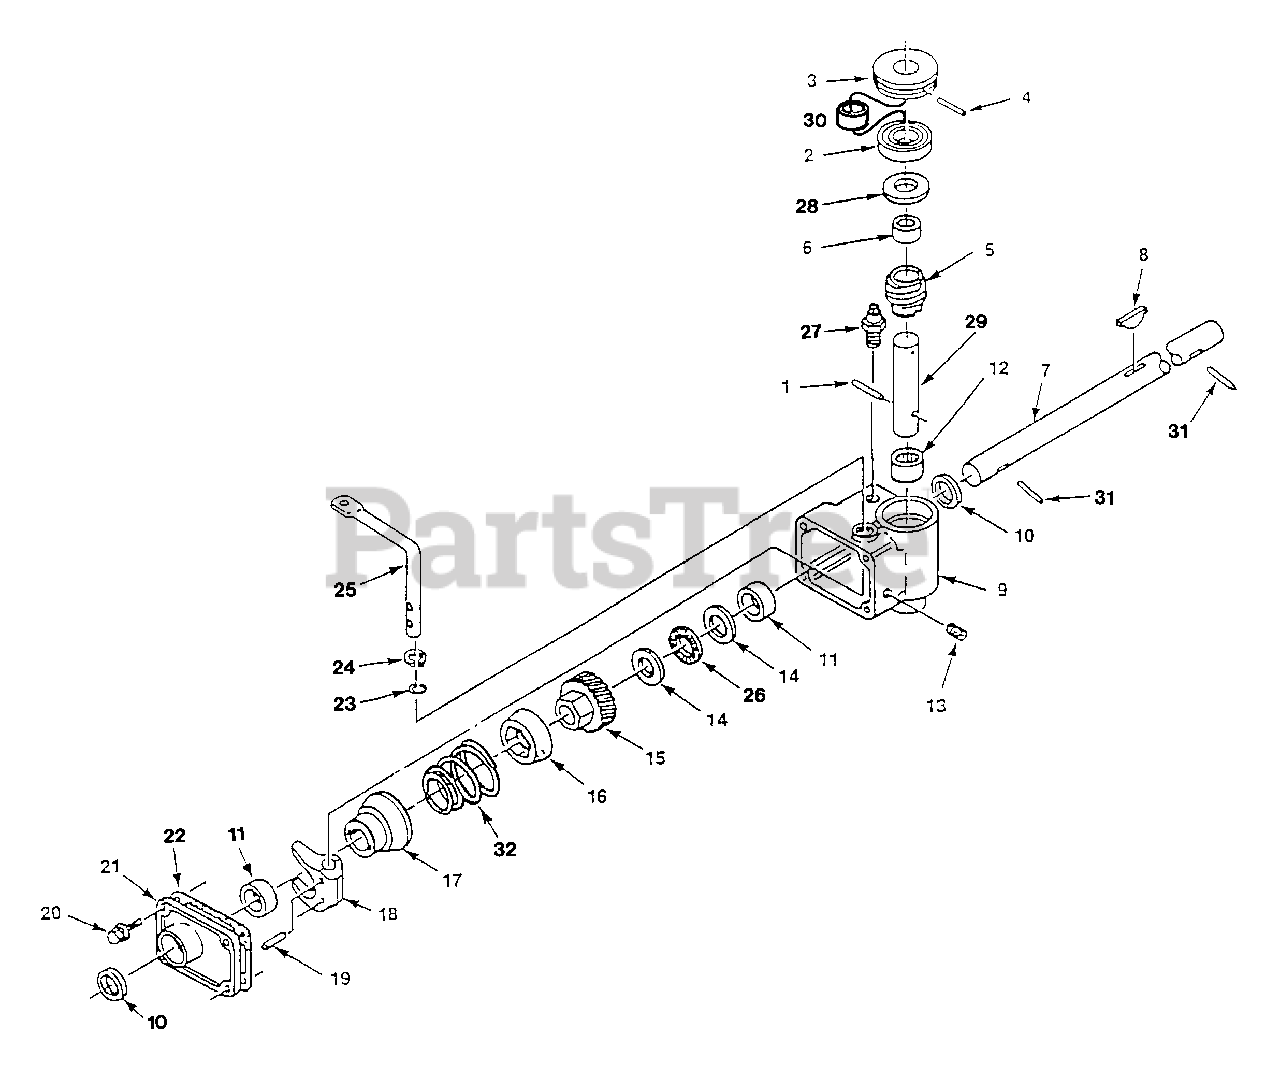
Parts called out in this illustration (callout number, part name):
1	Pin - Roll 3/16 x 7/8
2	Bearing - bail
3	Pulley - drive
4	Pin - Roll 3/32 x 1-1/4
5	Worm w/spacer
6	Spacer - worm
7	Shaft - drive
8	Key - Woodruff
9	Housing - gear
11	Bushing - sleeve
12	Bearing - needle
13	Plug - pipe
14	Race - thrust
15	Gear - helical
16	Cone - friction
17	Drum - clutch
18	Fork - shift
19	Pin - groove
20	Screw - hex 1/4-20 x 7/8 sems
21	Cover - gear box
22	Gasket - cover
24	Ring - retainer
25	Lever - shift
26	Bearing - needle
28	Washer - flat
29	Shaft - worm
30	Spacer - pulley
31	Pin - roll 1/8 x 7/8
32	Spring - clutch
